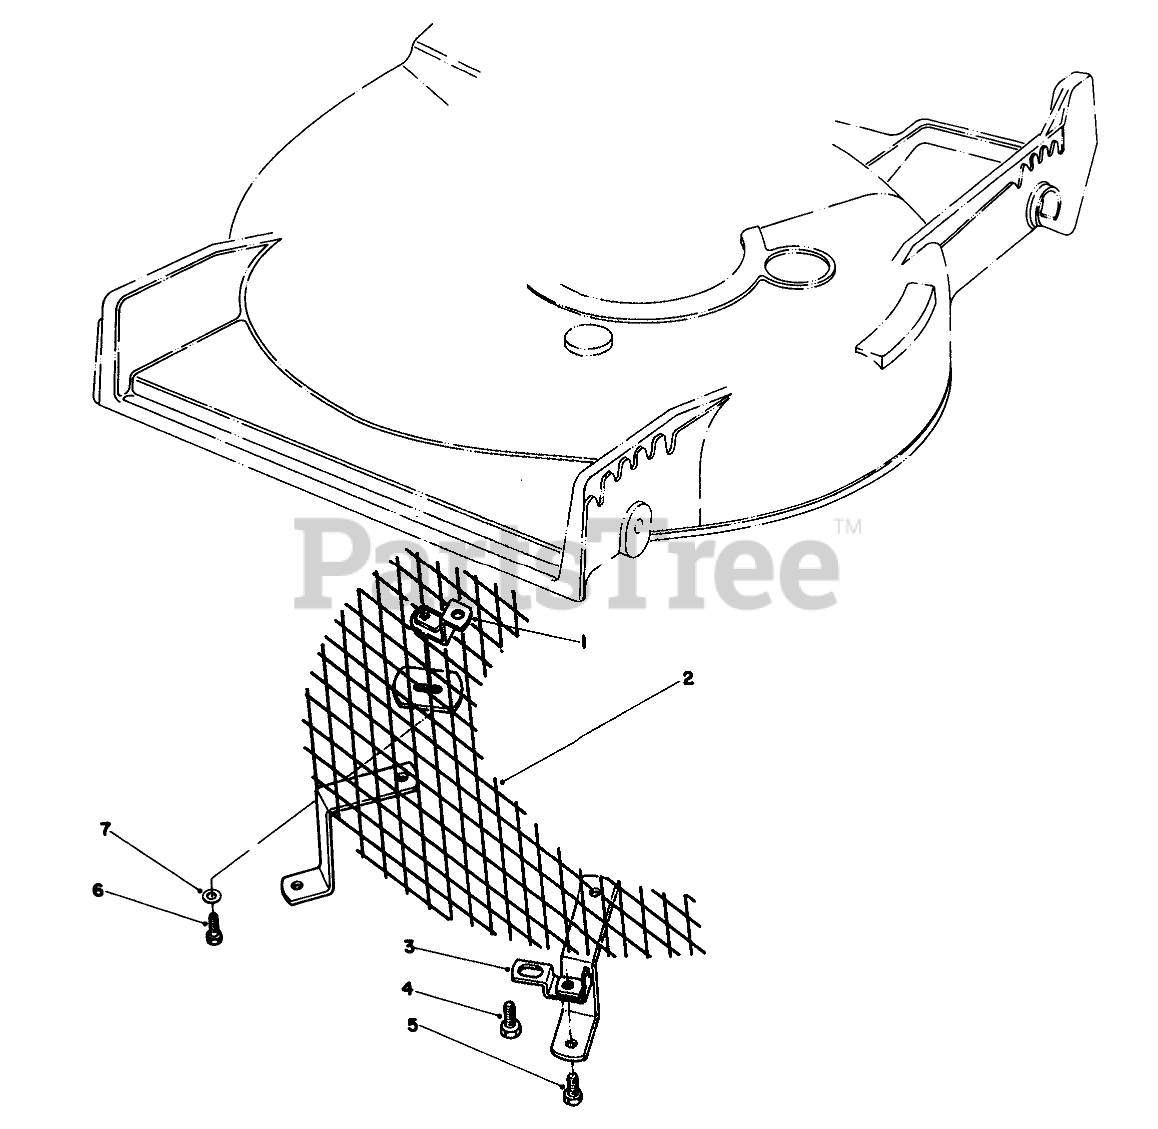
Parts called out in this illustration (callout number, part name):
1	BRACKET WA
2	SCREEN WA
3	MTG. BRACKET W.A.
4	SCREW-HWHTF
5	SCREW-HH
6	SCREW-HH
7	WASHER-FLAT
